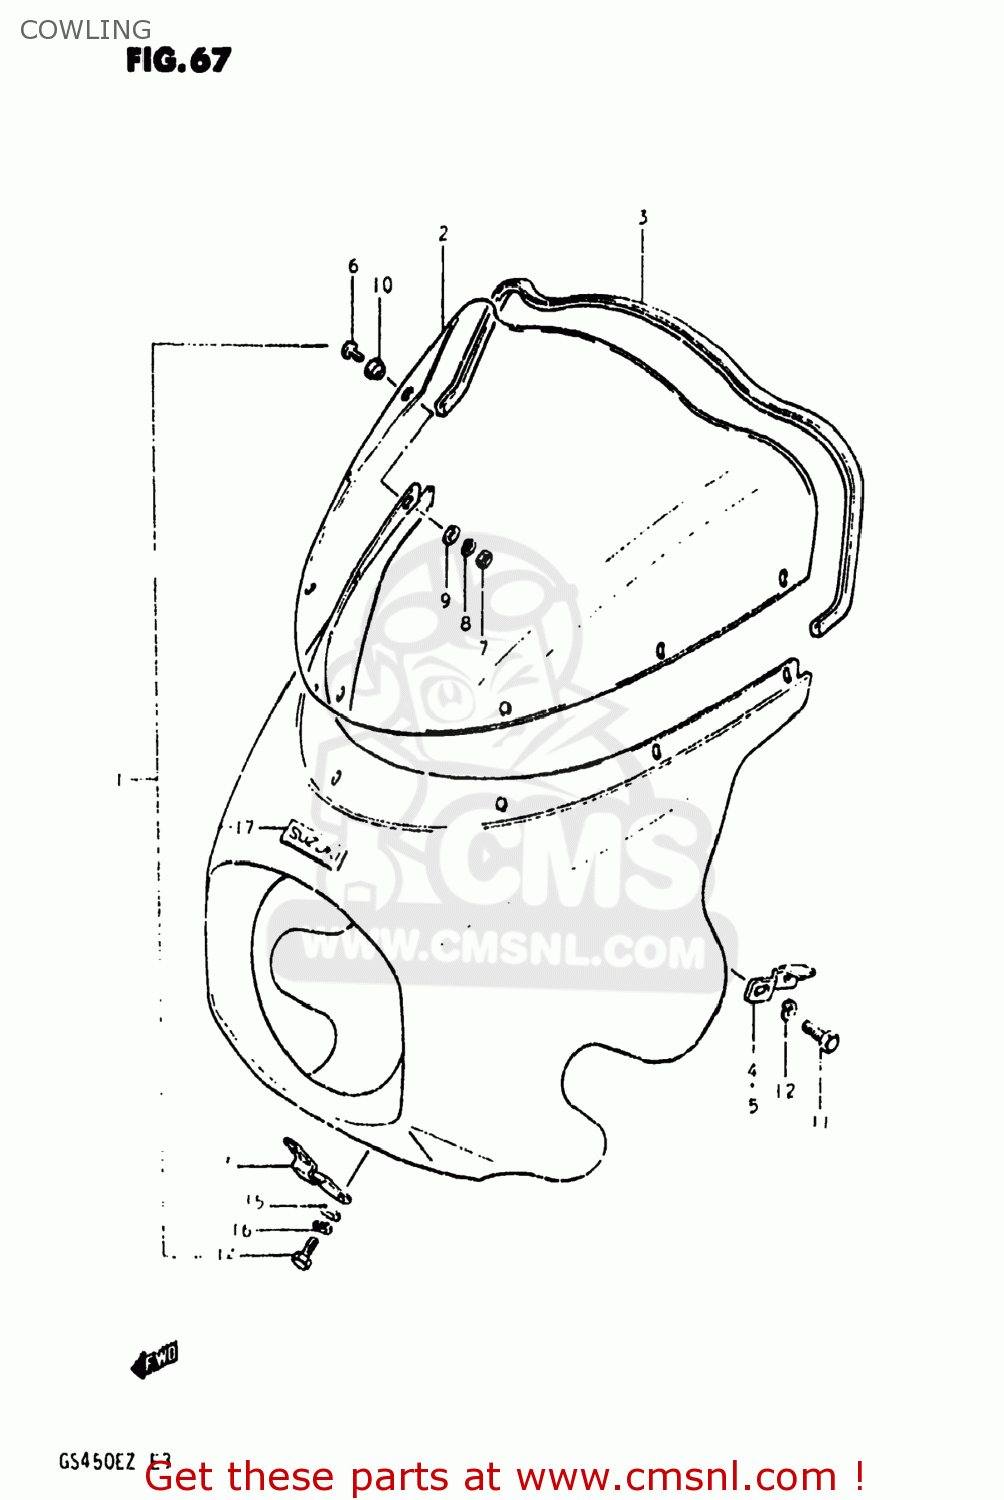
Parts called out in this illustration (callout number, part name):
1	COWLING ASSEMBLY
2	WINDOW,COWLING
3	MOLD,COWLING
4	BRACKET,COWLING,RIGHT
5	BRACKET, LH
6	SCREW M5X12 DIN 7985/N
7	NUT
8	LOCK WASHER
9	WASHER
10	CUSHION
11	BOLT
12	LOCK WASHER
13	BRACKET,COWLING,LOWER
14	BOLT
15	WASHER
16	LOCK WASHER
17	EMBLEM
